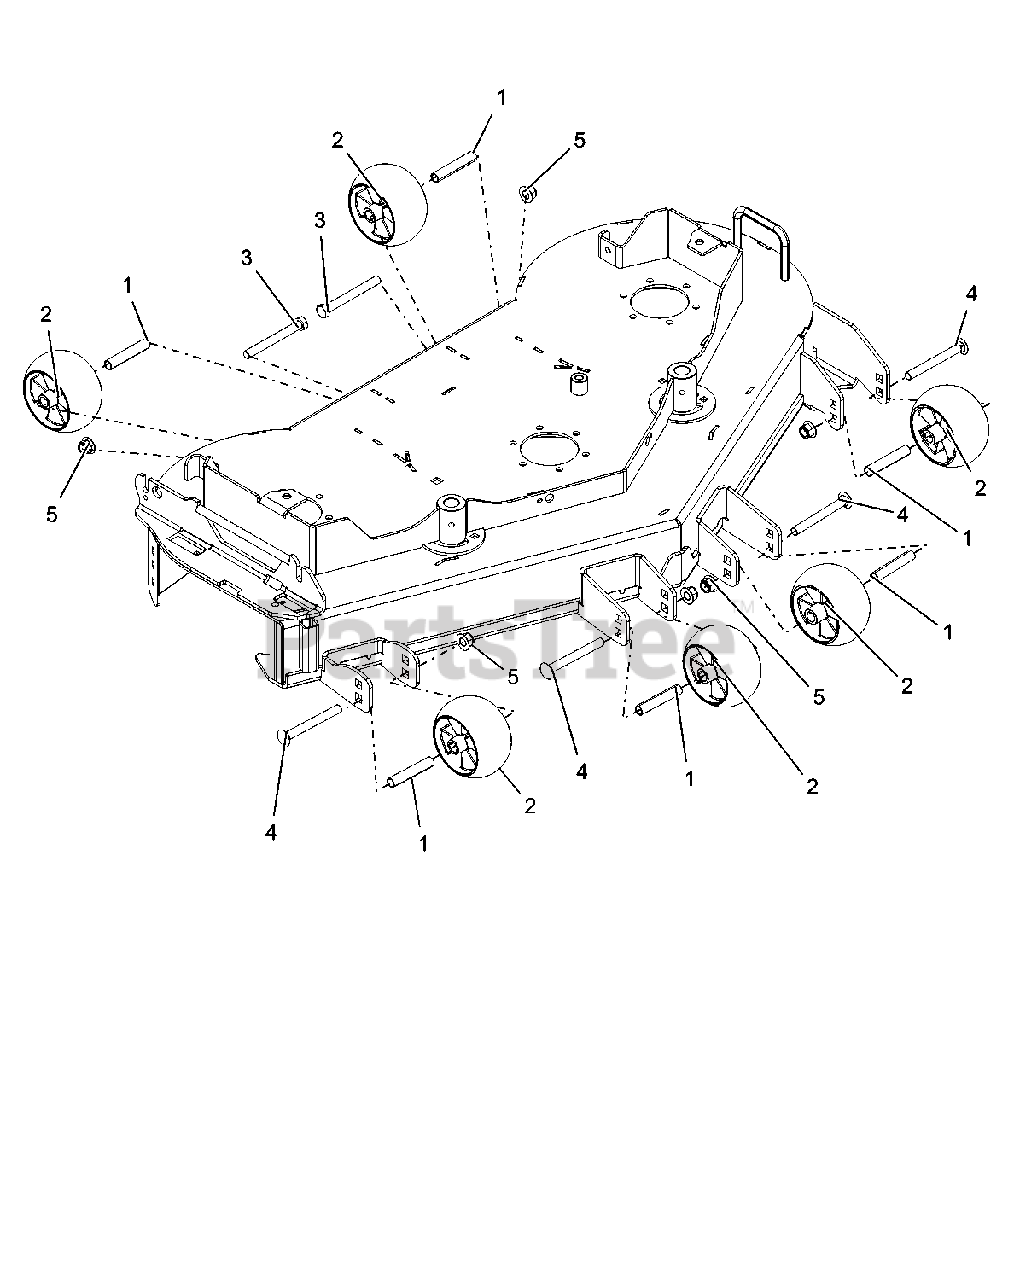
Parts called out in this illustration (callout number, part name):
1	SPACER, .510X.625X3.35
2	ANTI-SCALP WHEEL - 5X3 CTR
3	BLT-HEX .50-13X4.50 GR5 YWZC
4	BLT-RDHDSQNK .50-13X4.50 G5 YWZC
5	NUT-LK-NYL-FLG .50-13 YWZC
